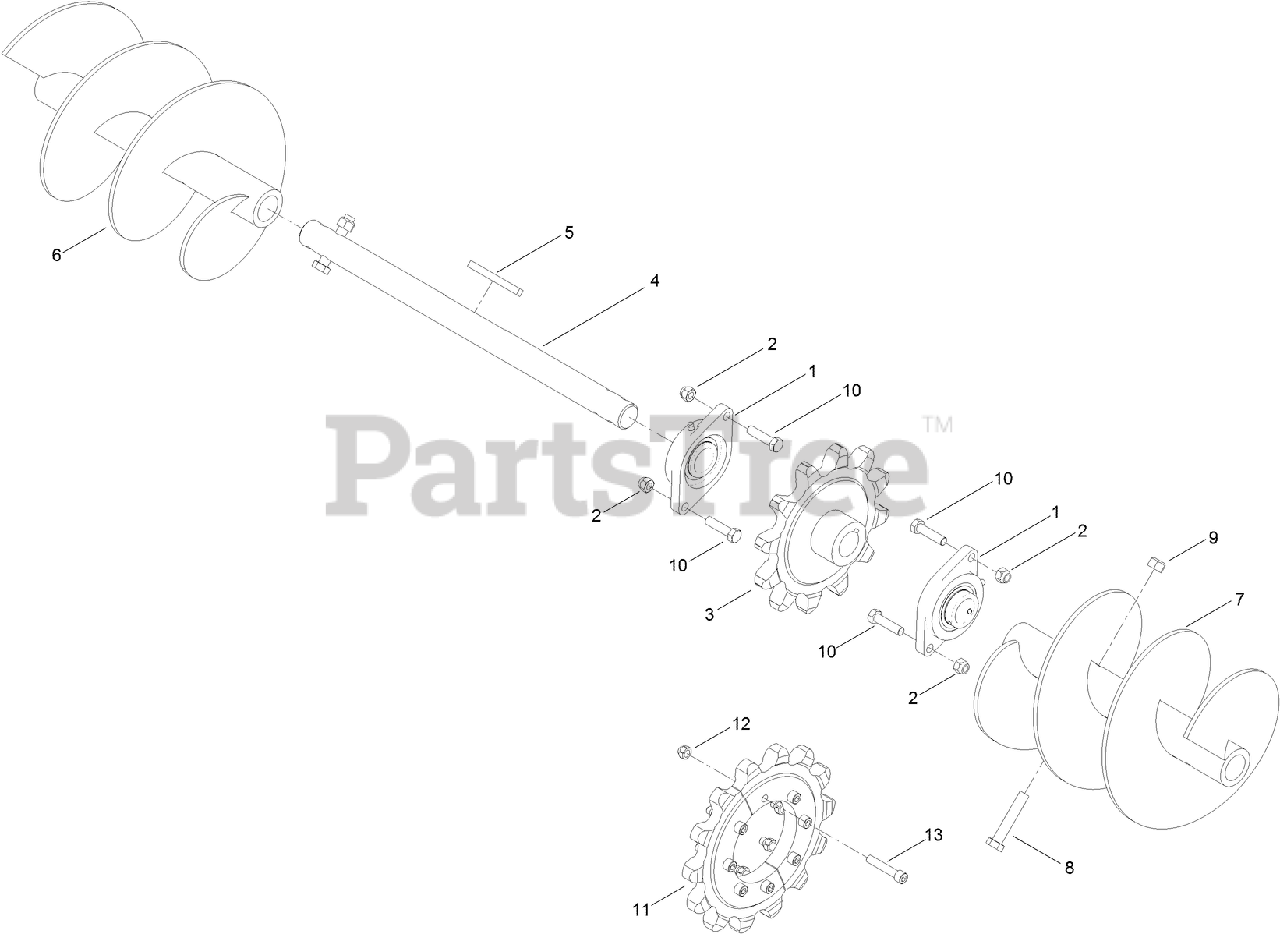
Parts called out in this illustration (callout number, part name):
1	BEARING-BALL, 2-BOLT FLANGE (2 IN)
2	NUT-LOCK, HEX
3	SPROCKET-12T
4	SHAFT-AUGER
5	KEY-SQUARE
9	NUT-LOCK
10	SCREW-HH
11	SPROCKET-SPLIT, 14T
12	NUT-HEX
13	SCREW-HSH
